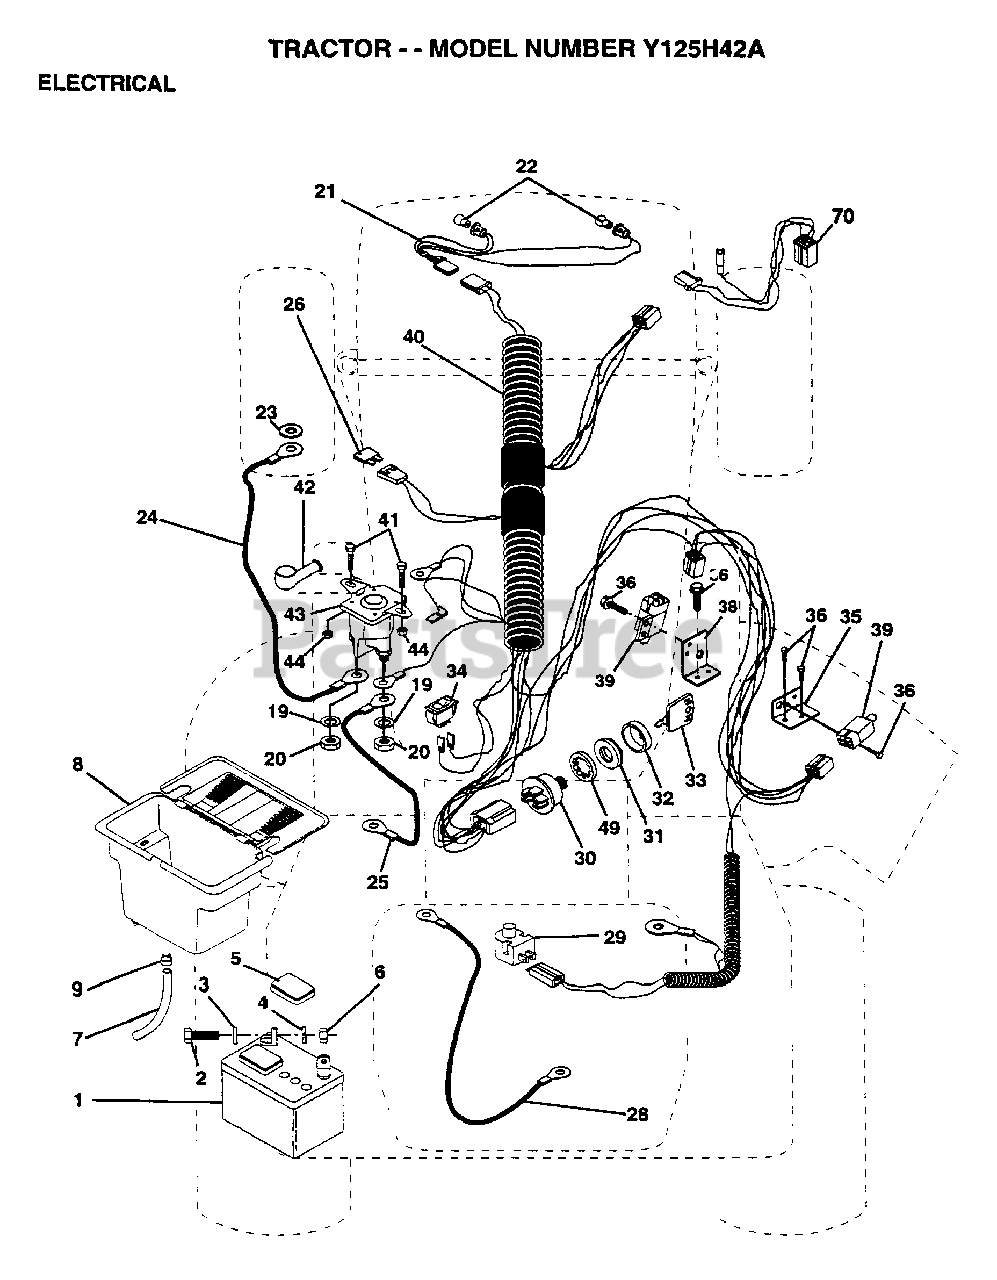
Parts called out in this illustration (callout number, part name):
2	BOLT LT
3	WASHER
4	LOCKWASHER
5	"CAP,BATTERY "
7	TUBE T
9	HOSE CLAMP T
20	NUT
21	"HARNESS,LIGHT SOC"
22	HEADLAMP BULB
23	LOCKWASHER
24	"CABLE T, BATTERY"
26	FUSE HYT
28	CABLE T
29	SWITCH SEAT
32	COVER KEY SWITCH
33	KEY MLD GEN DELTA
34	SWITCH LT
35	BRACKET LT
36	SCREW
38	BRACKET SWITCH IN
39	SWITCH INTERLOCKT
40	HARNESS IGN DASH
41	BOLT HXHD FIN
44	NUT HXKEP 1/4X20
49	LOCKWASHER
70	HARNESS ENG DUAL
